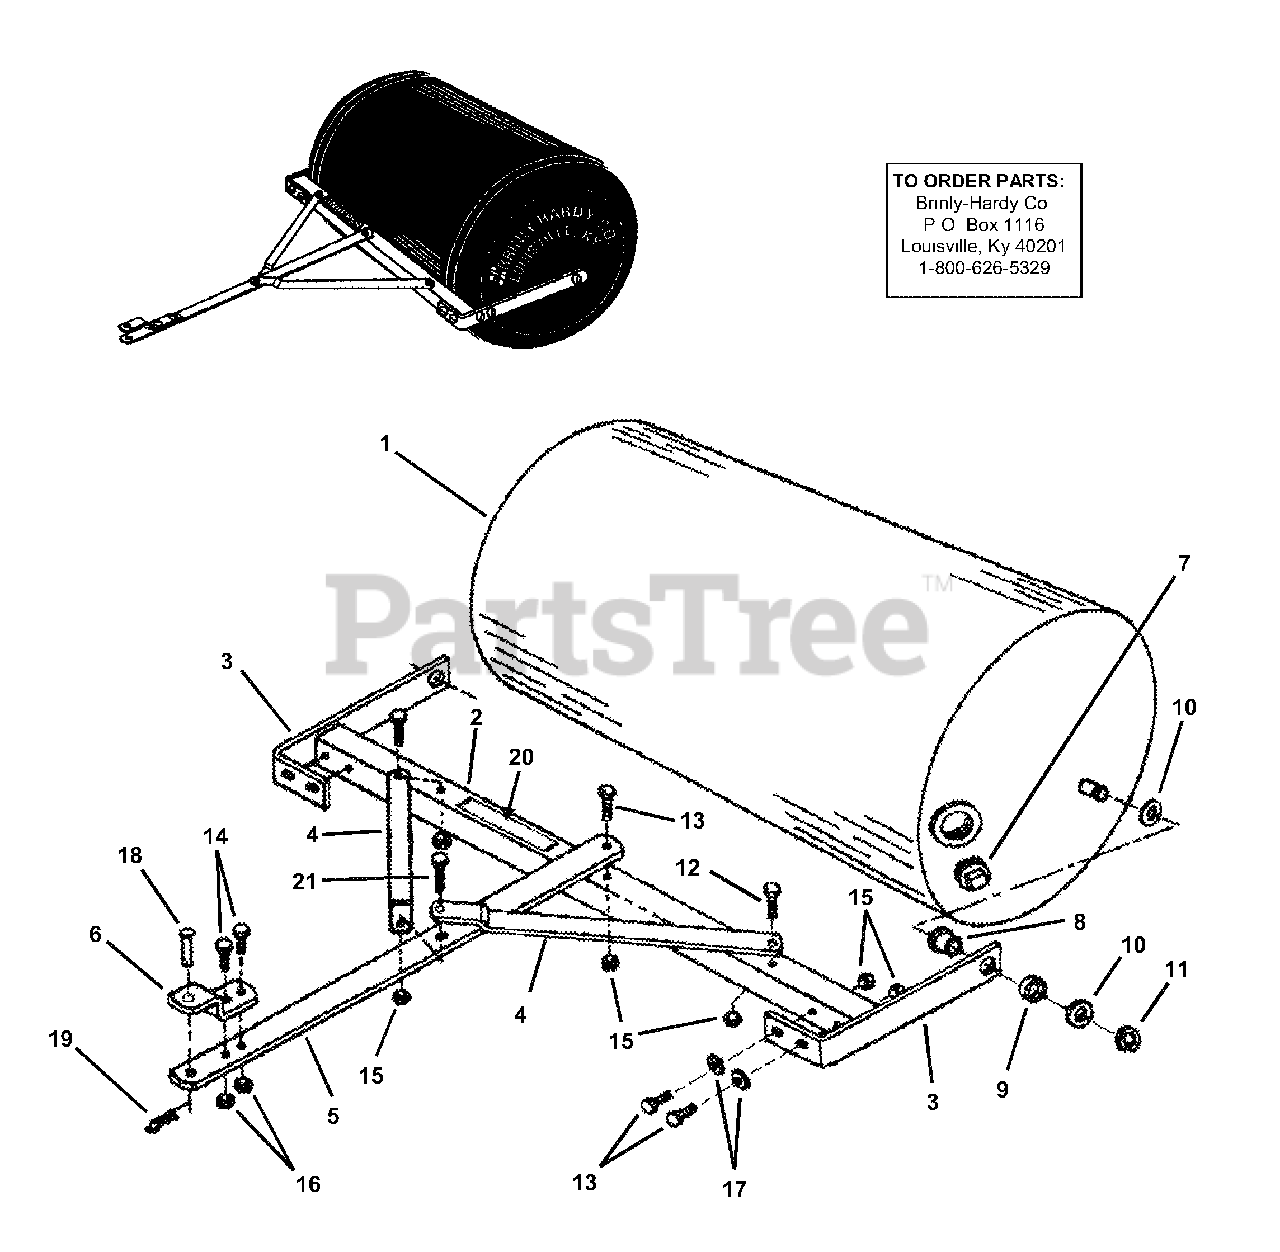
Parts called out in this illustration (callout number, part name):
1	DRUM, Roller
2	BAR, Scraper
3	BAR, Side
4	BRACE, Frame
8	BEARING
9	SPACER, Bearing
10	WASHER, Machine Bushing
11	"E" RETAINING RING Type 1
12	BOLT, 3/8 x 1" Hex
13	BOLT, 3/8 x 1-1/4" Hex
14	BOLT, 5/16 x 1-1/4" Hex
15	NUT, 3/8" Nylon Insert
16	NUT, 5/16" Nylon Insert
17	WASHER, 3/8" Plain
18	HITCH PIN, 1/2 x 2-3/4"
19	HAIRPIN COTTER, 1/8"
20	DECAL, Logo
21	BOLT, 3/8 x 1-1/2"
